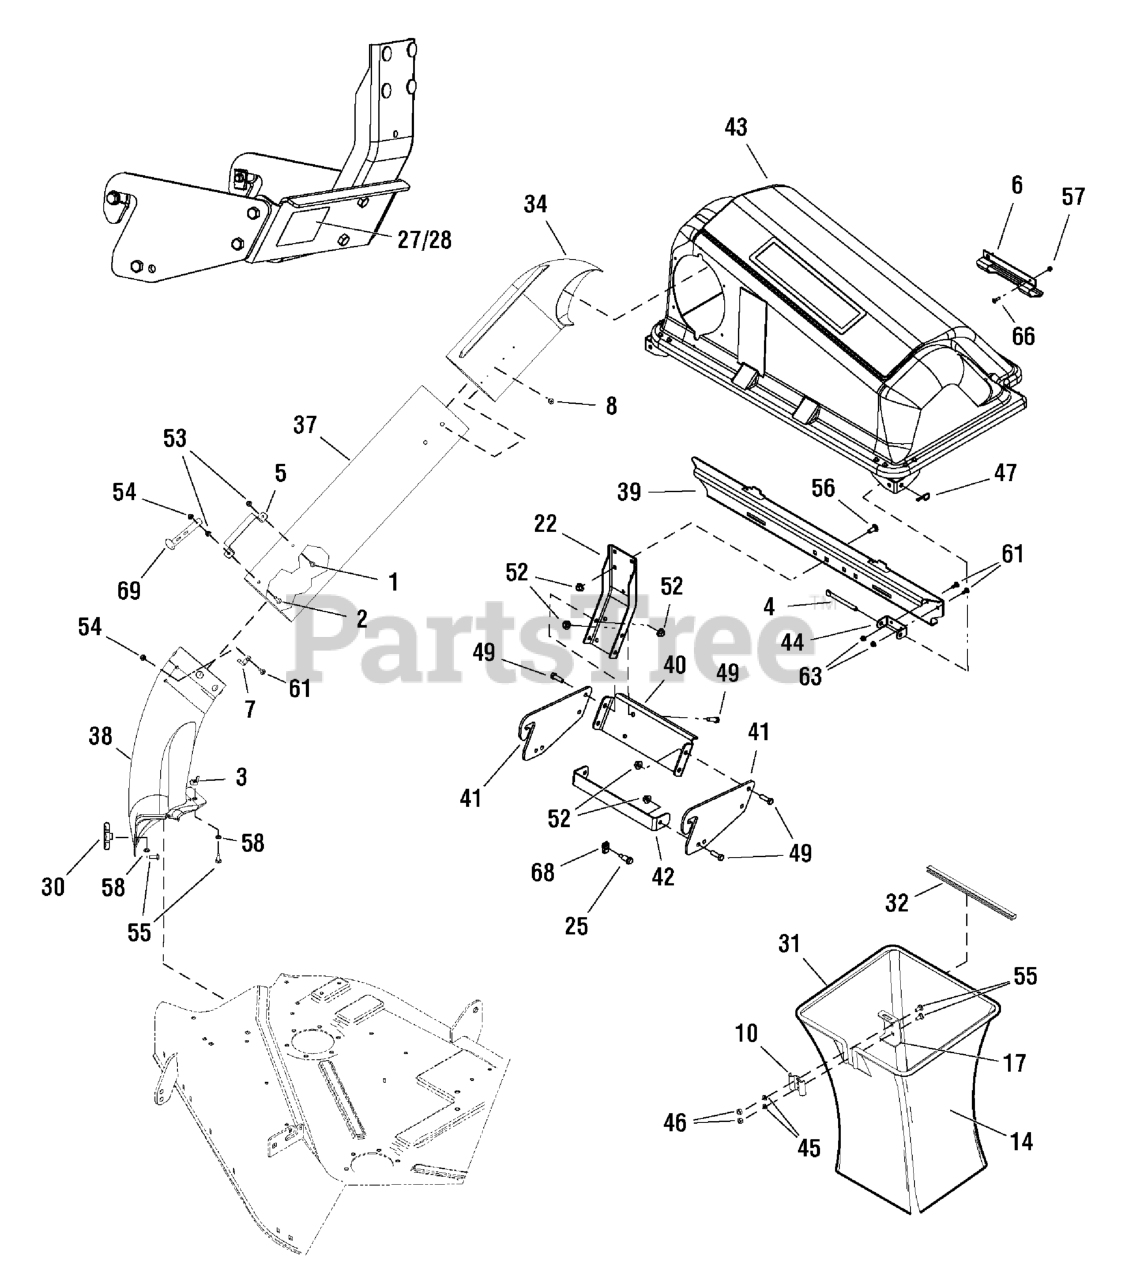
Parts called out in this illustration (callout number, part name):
1	SCREW, 1/4-20 x 1/2
2	SCREW, 1/4-20 x 1
3	WINGNUT, 5/16-18
4	PIN, Cover Hinge, 3/8 x 3-3/4
5	HANDLE, Connect Tube
6	HANDLE, Plastic
7	PIN, Latch
8	SCREW, 1/4 x 3/4
14	BAG, Grass
17	HANGER, Grass Bag Hoop,Twin
22	SUPPORT, Upright, Twin
25	BOLT, Shoulder, 5/16-18 x 1-5/8
27	* MYLAR OVERLAY
28	* STICKER, Serial Number
30	KNOB, 5 Lobe, 5/16-18 x 3/4
31	HOOP, Twin Catcher
32	EDGING, 12 Long PVC
34	ELBOW, Upper Tube
37	Tube, Clear
38	Tube, Boot, Black
39	CROSS SUPPORT
40	BRACKET, Upright
41	PLATE, Bagger Mount
42	BRACKET, Hitch Support
43	COVER & SCREEN ASSEMBLY
44	PIVOT, Hinge
45	LOCKWASHER, Spring, 5/16
46	NUT, Hex 5/16-18
47	PIN, Quick, 1-7/8
49	CAPSCREW, Hex Head, 3/8-16 x 1-1/4, G5
52	NUT, Hex Flange, 3/8-16 Whiz Lock
53	NUT, Hex, 1/4-20
54	NUT, Hex Flange, 1/4-20 Top Lock, Small
55	BOLT, Carriage, 5/16-18 x 3/4 G5
56	BOLT, Carriage, 3/8- 16 x 1, G5
57	NUT, Hex, Ny-Lock, 10-24
58	NUT, Push, 5/16
61	BOLT, Carriage, 1/4-20 x 5/8
63	NUT, Hex Flange, 1/4-20 Whiz Lock, Small
66	SCREW, Truss Head, Phillips, #10-24 x 0.75
68	NUT, Speed, 5/16-18
69	STRAP, Hood, Rubber
